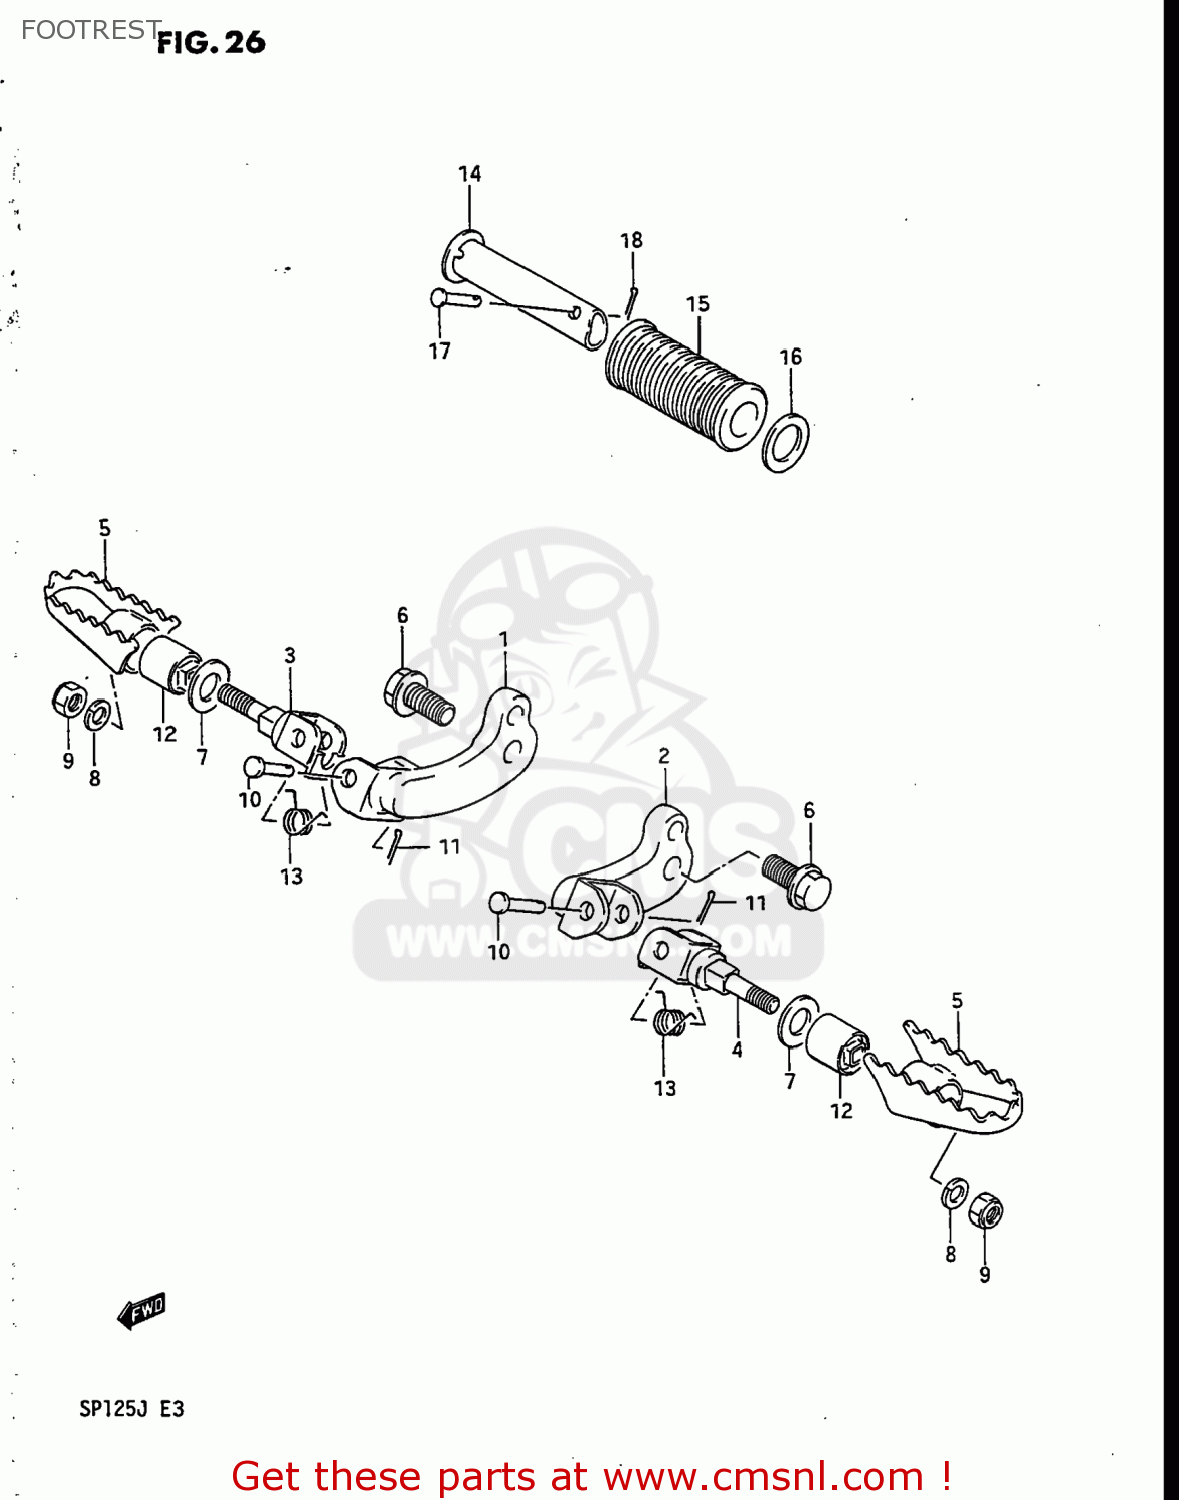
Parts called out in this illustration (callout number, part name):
1	BAR,FR FOOTREST,R
2	BAR,FR FOOTREST,L
3	BRACKET,FRONT FOOTREST
4	HOLDER COMP,FRONT FOOT
5	FOOTREST,FR
6	BOLT
7	WASHER
8	WASHER,LOCK
9	NUT
10	PIN
11	PIN
12	BUSH
13	SPRING
14	BAR,FOOTREST RUBBER
15	RUBBER,PILLION FOOTREST
16	WASHER (19.5X32X2)
17	PIN
18	PIN 20X20
